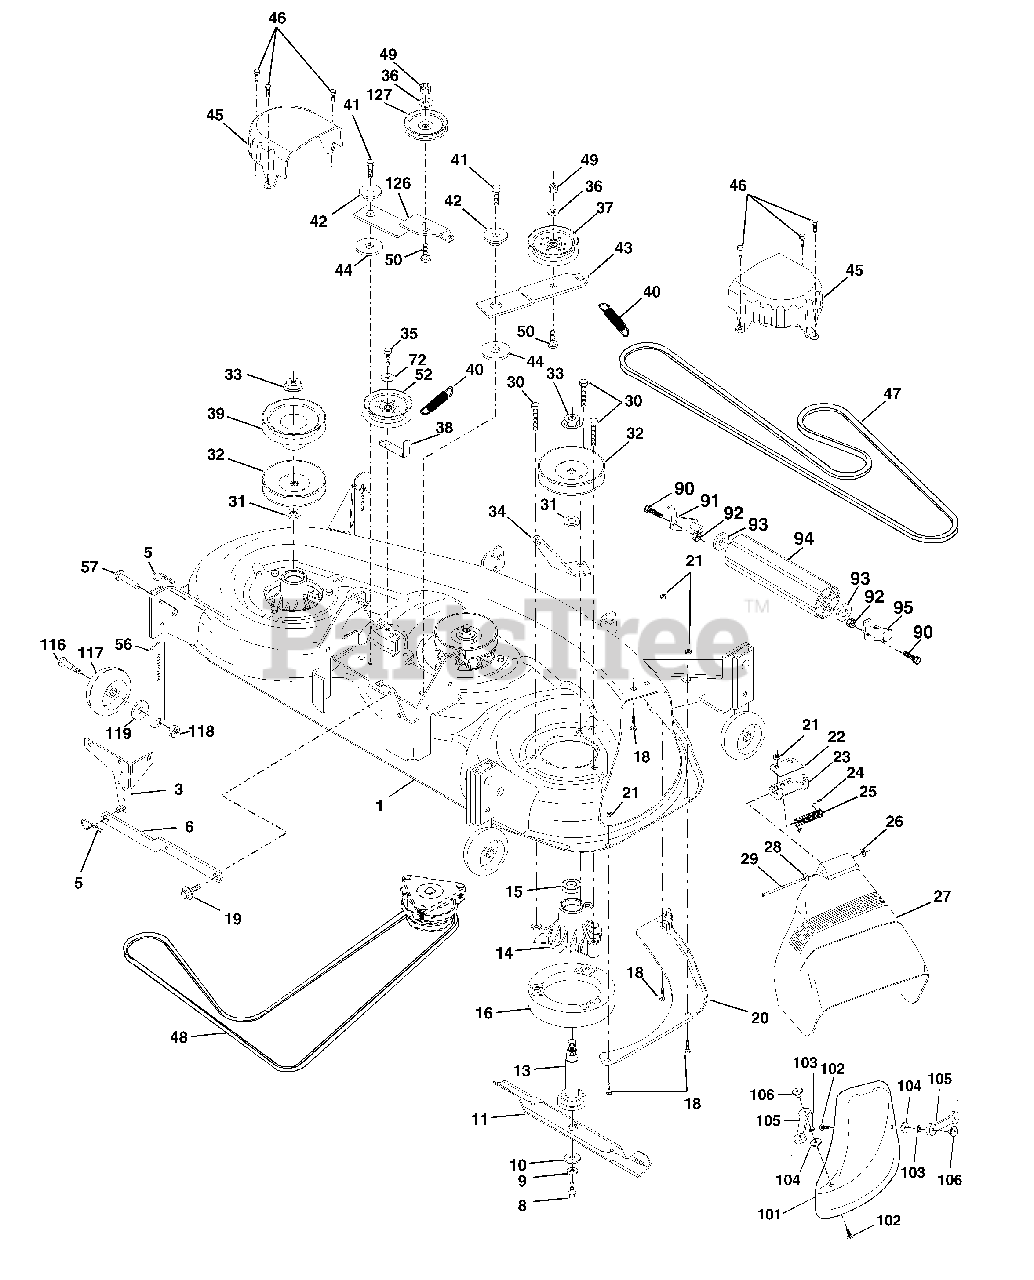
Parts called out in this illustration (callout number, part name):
1	Deck Weldment Mower HD 46 WAD
3	Bracket Asm., Sway Bar
5	Retainer Spring
6	Arm, Suspension, Rear (Sway Bar)
8	Bolt, Patched 3/8-24 x 1-1/4 Gr. 8
9	Washer, Lock Hvy., Unplated 3/8
10	Washer, Hard Blade, Mower Vented
11	Blade, 46" High Performance
11	Blade, 46" Mulching
13	Shaft Asm. w/Lower Bearing
14	Housing, Mandrel
15	Bearing, Ball, Mandrel
16	Stripper, Mower Round
18	Bolt, Carriage 5/16-18 x 5/8
19	Bolt, Hex Head, Shoulder 5/16-18
20	Baffle, Vortex Mower 46"
21	Nut, Crownlock 5/16-18 UNC
22	Stiffener, Bracket
23	Bracket, Deflector
24	Cap, Sleeve
25	Spring, Torsion, Deflector
27	Shield, Deflector Mower
28	Washer 11/32 x 5/8 x 16 Ga.
29	Rod, Hinge
30	Screw, Thdroll, Washer Head
31	Washer, Spacer Mower Vented
32	Pulley, Mandrel
33	Nut, Flg. Top Lock Cntr. 9/16
34	Anchor, Spring Deck 46"
35	Screw, Thdroll 3/8-16 x 1-3/4 Tytt
36	Washer 13/32 x 13/16 x 16 Ga.
37	Pulley, Idler, Flat
38	Keeper, Belt, Idler
39	Pulley, Idler, Driven
40	Spring, Secondary 44/46/50 Vent
41	Screw, Thdroll 3/8-16 x 1-1/4
42	Spacer, Retainer
43	Arm, Idler Secondary
44	Washer, Hardened
45	Cover, Mandrel Deck
46	Screw, Thdroll. 1/4-20 x 5/8
47	V-Belt, Mower, Secondary
48	V-Belt, Mower, Primary
49	Nut, Crownlock 3/8-16 UNC
50	Bolt, Carriage 3/8-16 x 1-1/2 Gr. 5
52	Pulley Idler Flat 46 Pri. Drive
56	Bar Pnt Adjusting Wheel Gauge
57	Pin Head Rivet
72	Washer 13/32 x 1 x 16 Ga.
90	Bolt, Fin, Hex 3/8-16 UNC x 1
91	Bracket, Asm Noseroller, LH
92	Nut, Lock, Hex w/Ins 3/8-16UNC
93	Washer 17/32 x 7/8 x 16 Ga.
94	Roller, Nose 38 & 42
95	Bracket, asm Noseroller RH
101	Cover, Mulching
102	Screw
103	Washer, Lock #10
105	Latch Asm. Bagger
106	Nut, Weld
116	Bolt, Shoulder
117	Gauge Wheel
118	Nut, Centerlock 3/8-16 UNC
119	Washer 3/8 x 7/8 x 14 Ga.
126	Arm, Idler, Primary Deck 46"
127	Pulley, Idler, V-Groove Dim. 4.25
